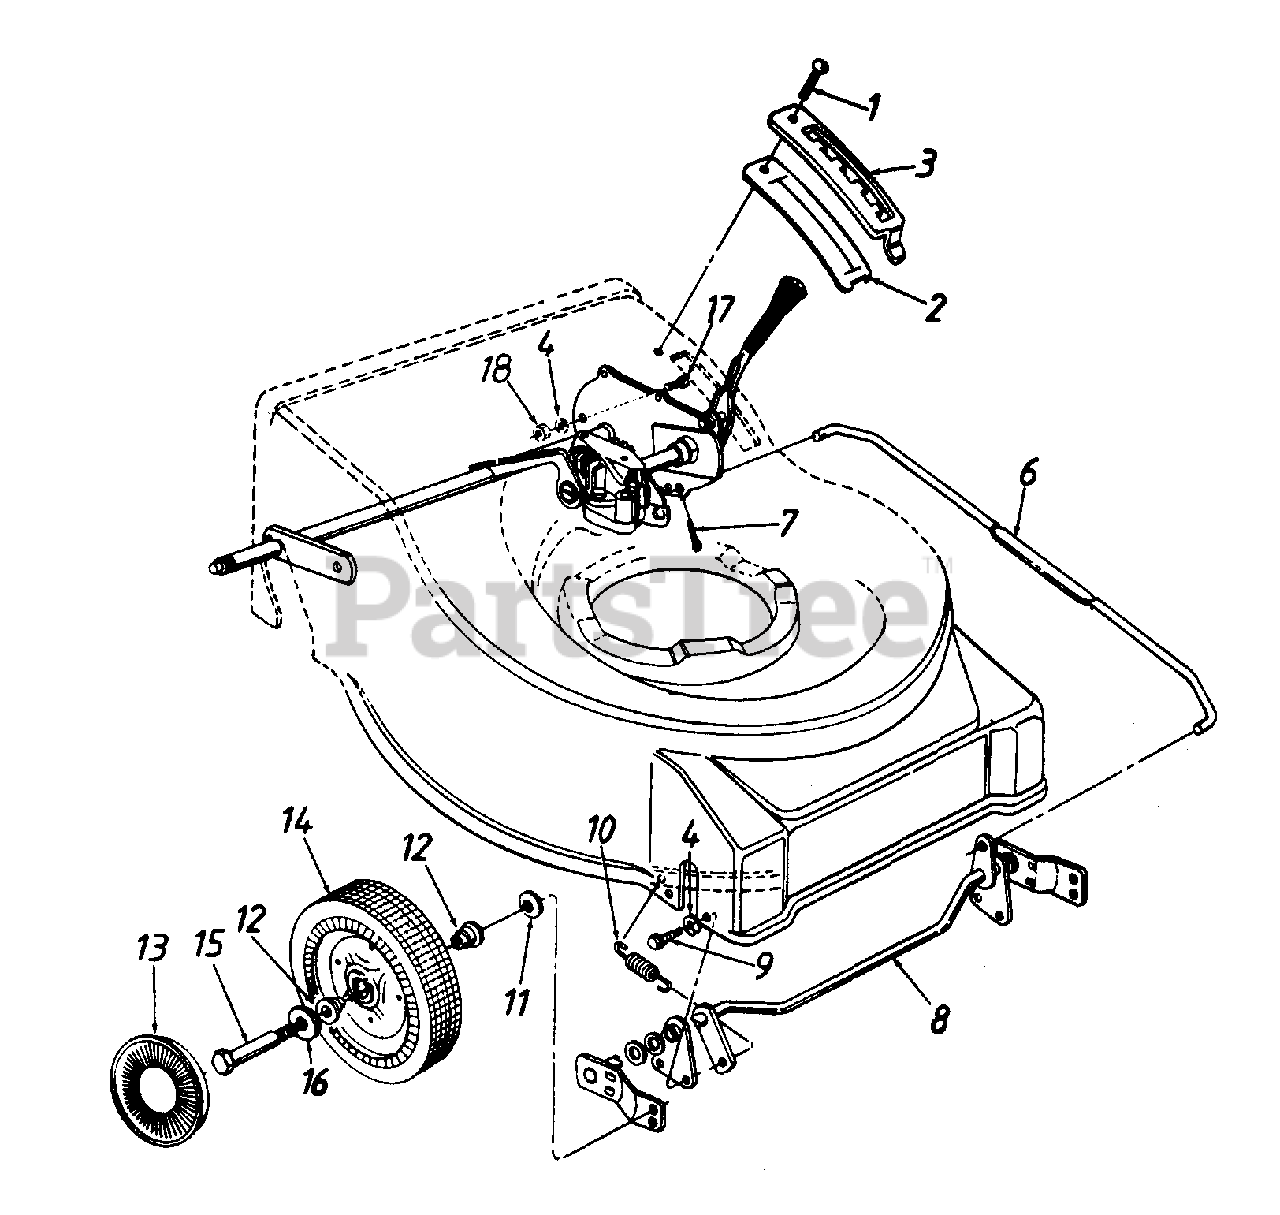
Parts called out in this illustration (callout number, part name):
1	Torx Mach. AB-Tap Scr. 1/4 x .62" Lg.
2	Height Adjustment Support
3	Height Adjustment Plate
4	L-Wash. 1/4" I.D.
6	Height Adj. Connecting Rod
7	Cotter Pin 3/32" Dia.
9	Hex L-Wash. Hd. AB-Tap Scr. 1/4 x .38"
10	Extension Spring 2.39" Lg.
11	Bell-Wash. .380" I.D. x .88"
12	Ball Bearing 1/2" I.D.
13	Hub Cap (See Below)
14	Wheel Ass'y. Comp.-Front
15	Shld. Bolt ,498" Dia. x 1.45"
16	Wave Wash. .51" I.D. x .78"
17	Mach. Scr. 1/4-20 x .5" Lg.
18	Hex Jam Nut 1/4-20 Thd.
